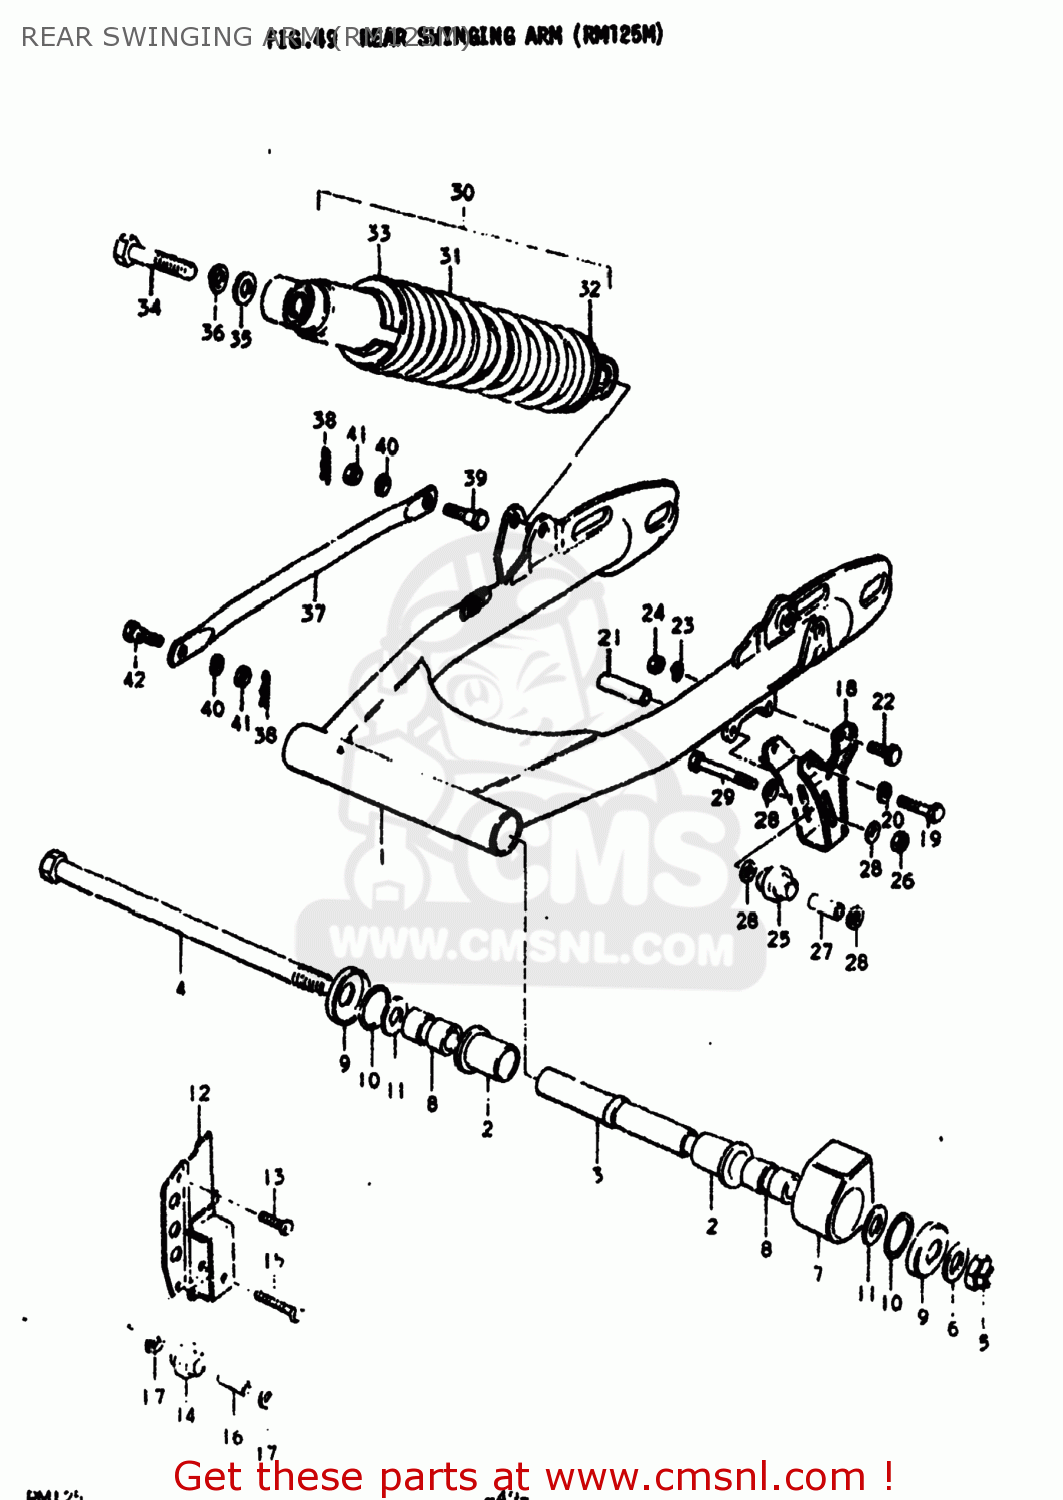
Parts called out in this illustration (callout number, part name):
1	SWING ARM ASSEMBLY,REAR
2	BUSHING
3	SPACER,SWING ARM,CENTER
4	SHAFT,PIVOT
5	NUT
6	WASHER
7	BUFFER,CHAIN TOUCH DEFENSE
8	SPACER,RR SWGARM PIVOT
9	COVER,SWGARM BUSH DUST SEAL
10	O RING(D:2,ID:24.5)
11	WASHER(12.5X24X2.3)
12	PLATE,CHAIN FRONT GUIDE
13	BOLT
14	ROLLER,CHAIN GUIDE
15	BOLT
16	SPACER
17	WASHER (6.5X13X2.3)
18	GUIDE
19	BOLT
20	LOCK WASHER
21	SPACER
22	BOLT
23	LOCK WASHER
24	NUT
25	ROLLER,CHAIN GUIDE
26	NUT (6MM)
27	SPACER
28	WASHER
29	BOLT
30	ABSORBER ASSEMBLY,REAR SHOCK
31	SPRING
33	GUIDE,SPRING
34	BOLT 10X40
35	WASHER
36	LOCK WASHER
37	TORQUE LINK,REAR
38	CLIP
39	BOLT(8X26.5)
40	LOCK WASHER
41	NUT
42	BOLT(8X22)
